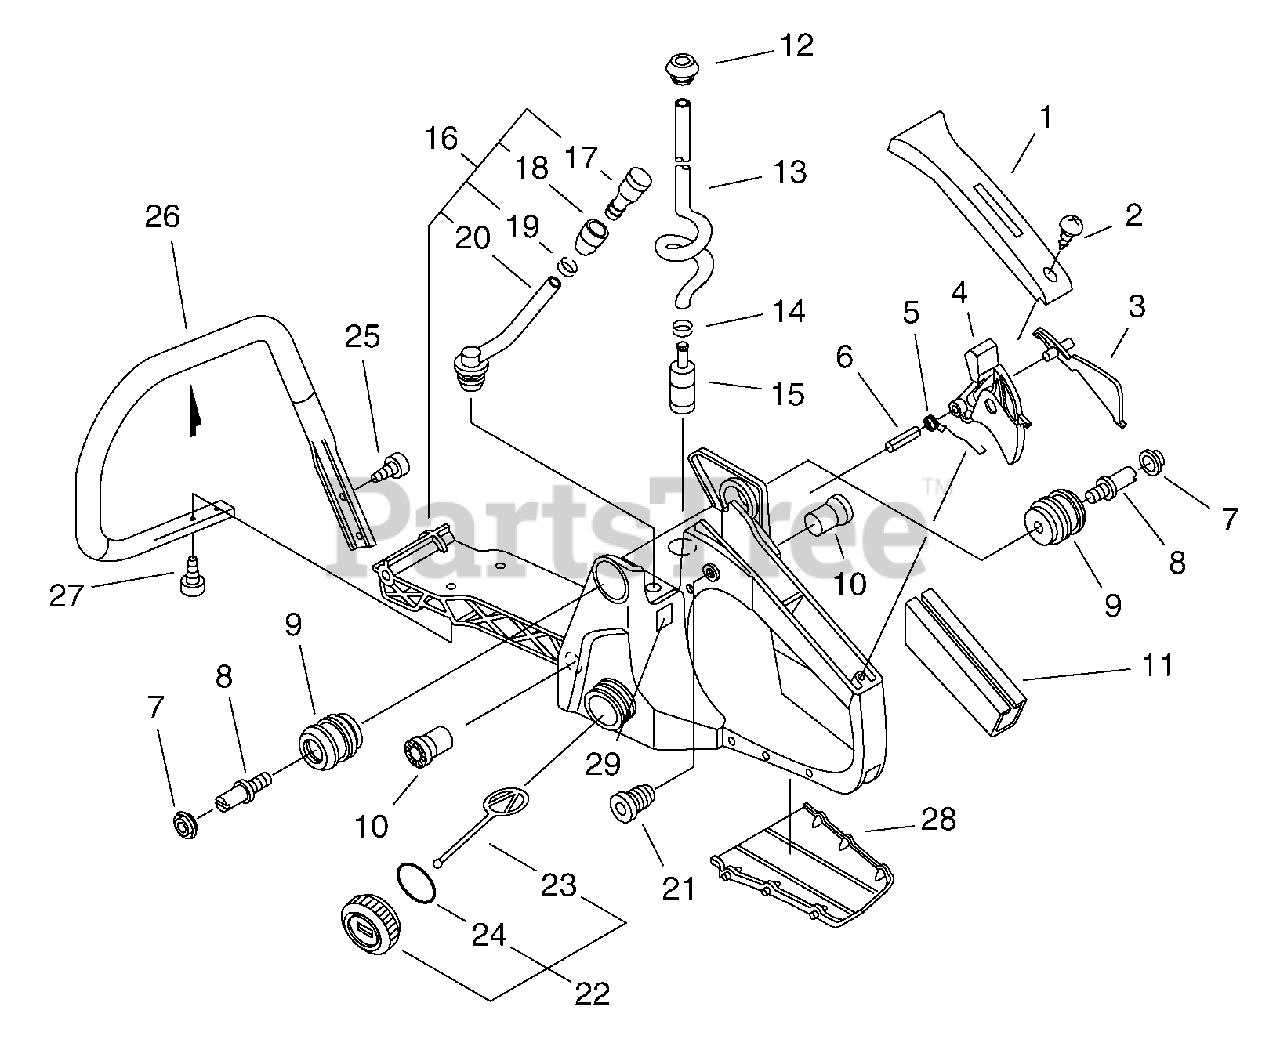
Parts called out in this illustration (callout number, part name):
1	COVER, HANDLE
2	SCREW 4×14
3	LOCKOUT, THROTTLE
4	TRIGGER, THROTTLE
5	SPRING, TORSION
6	PIN, SPRING 4×30
7	CAP, CUSHION
9	CUSHION 5
10	CUSHION 5
11	GRIP, HANDLE
13	PIPE, FUEL 3×6×165
14	CLIP 6.5 MM
15	FILTER, FUEL
16	REAR HANDLE ASSY
17	VENT ASSY
18	HOLDER, VENT
19	CLIP 6.5 MM
20	GROMMET, W/VENT PIPE 3×6×105
22	CAP ASSY, FUEL
23	CONNECTOR, CAP L= 60 MM
24	O-RING 22
25	SCREW TAPPING 5×20
26	HANDLE, FRONT
27	SCREW TAPPING 5×16
28	SHIELD, SNOW
29	LABEL, STOP
